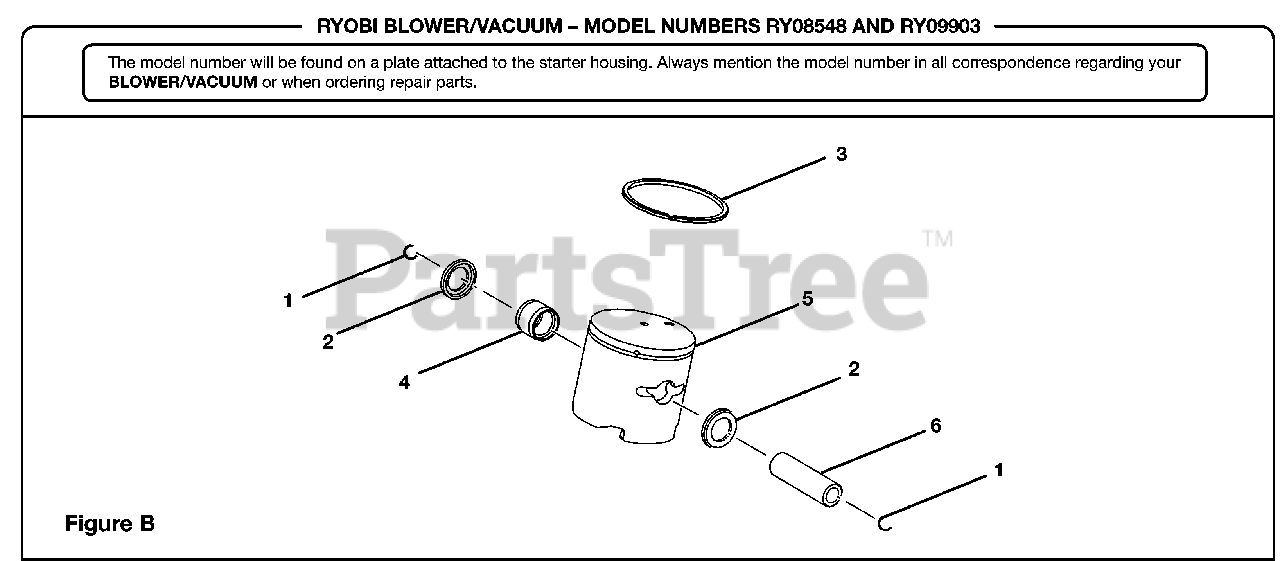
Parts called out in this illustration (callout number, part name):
1	Circlip Pin
2	Washer
3	Piston Ring
4	Needle Bearing
6	Piston Pin
